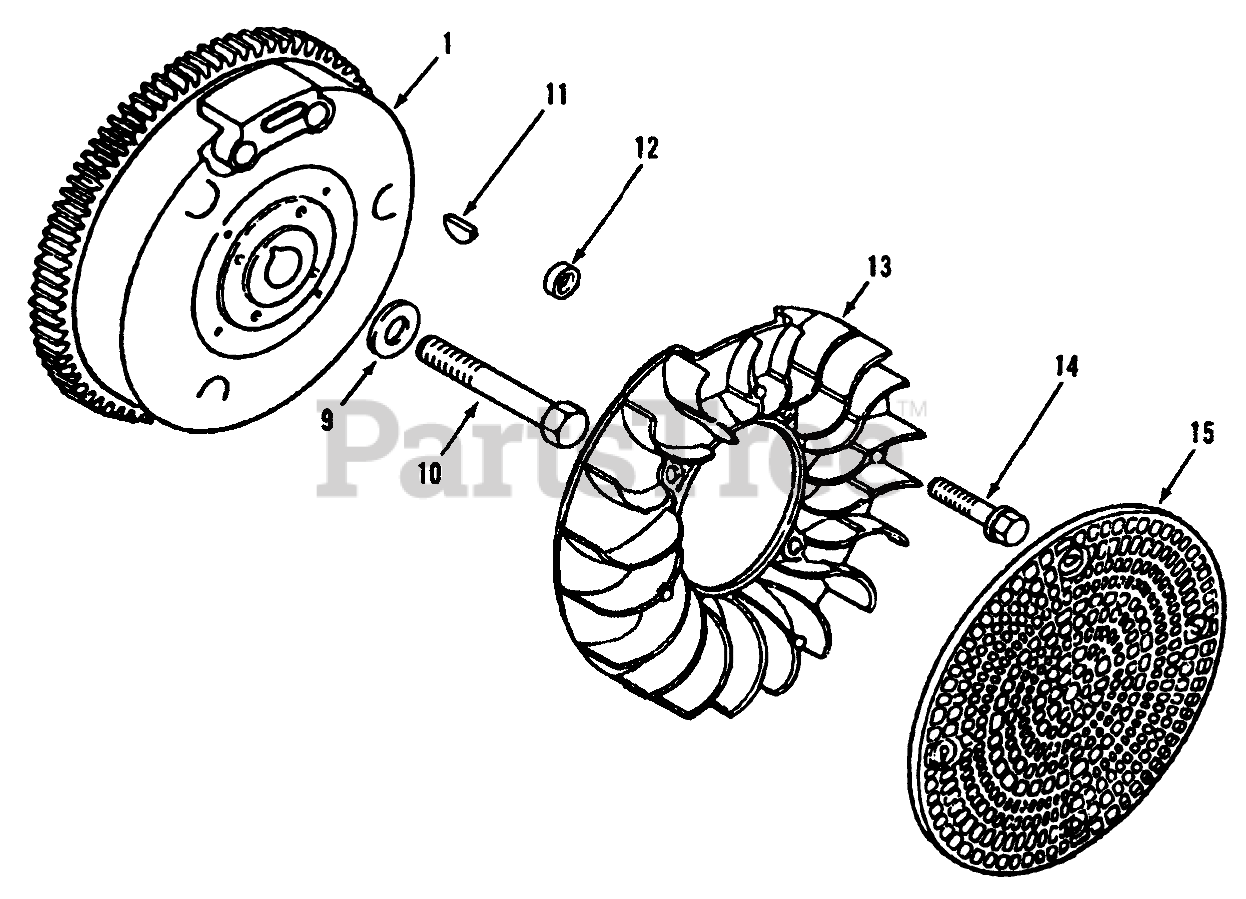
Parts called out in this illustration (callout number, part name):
1	KOHLER 47-025-53
9	KOHLER 52-468-15
10	KOHLER 25-086-24
11	KOHLER X-46-3
12	KOHLER 25-089-02
13	KOHLER 25-157-01
14	KOHLER 25-086-21
15	KOHLER 25-162-01
